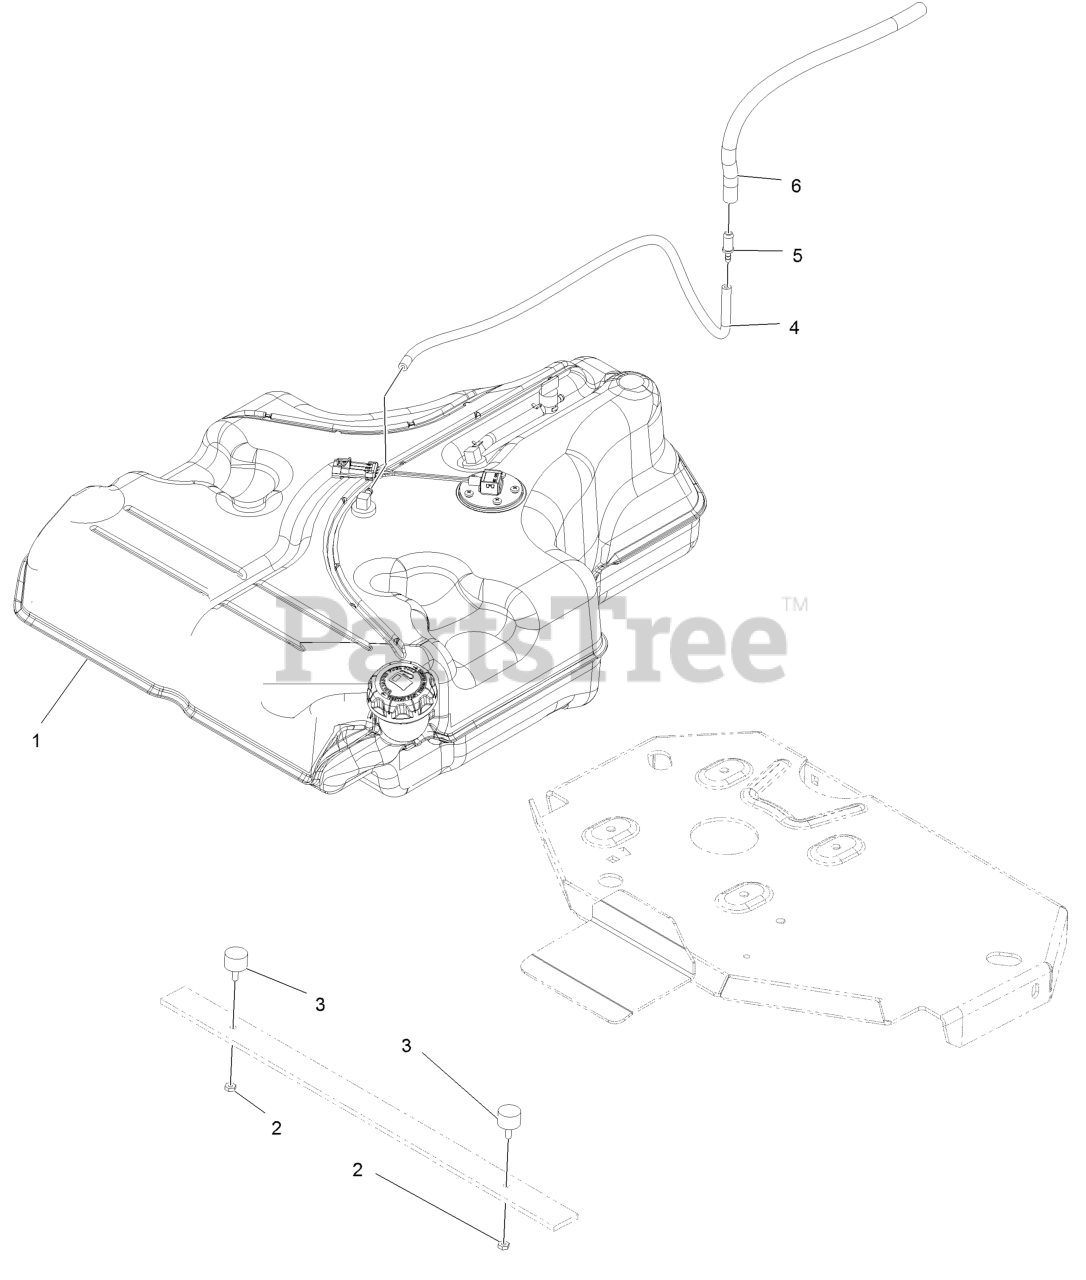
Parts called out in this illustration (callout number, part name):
2	NUT-JAM
4	HOSE-FUEL
5	FITTING-STRAIGHT
6	HOSE-FUEL
